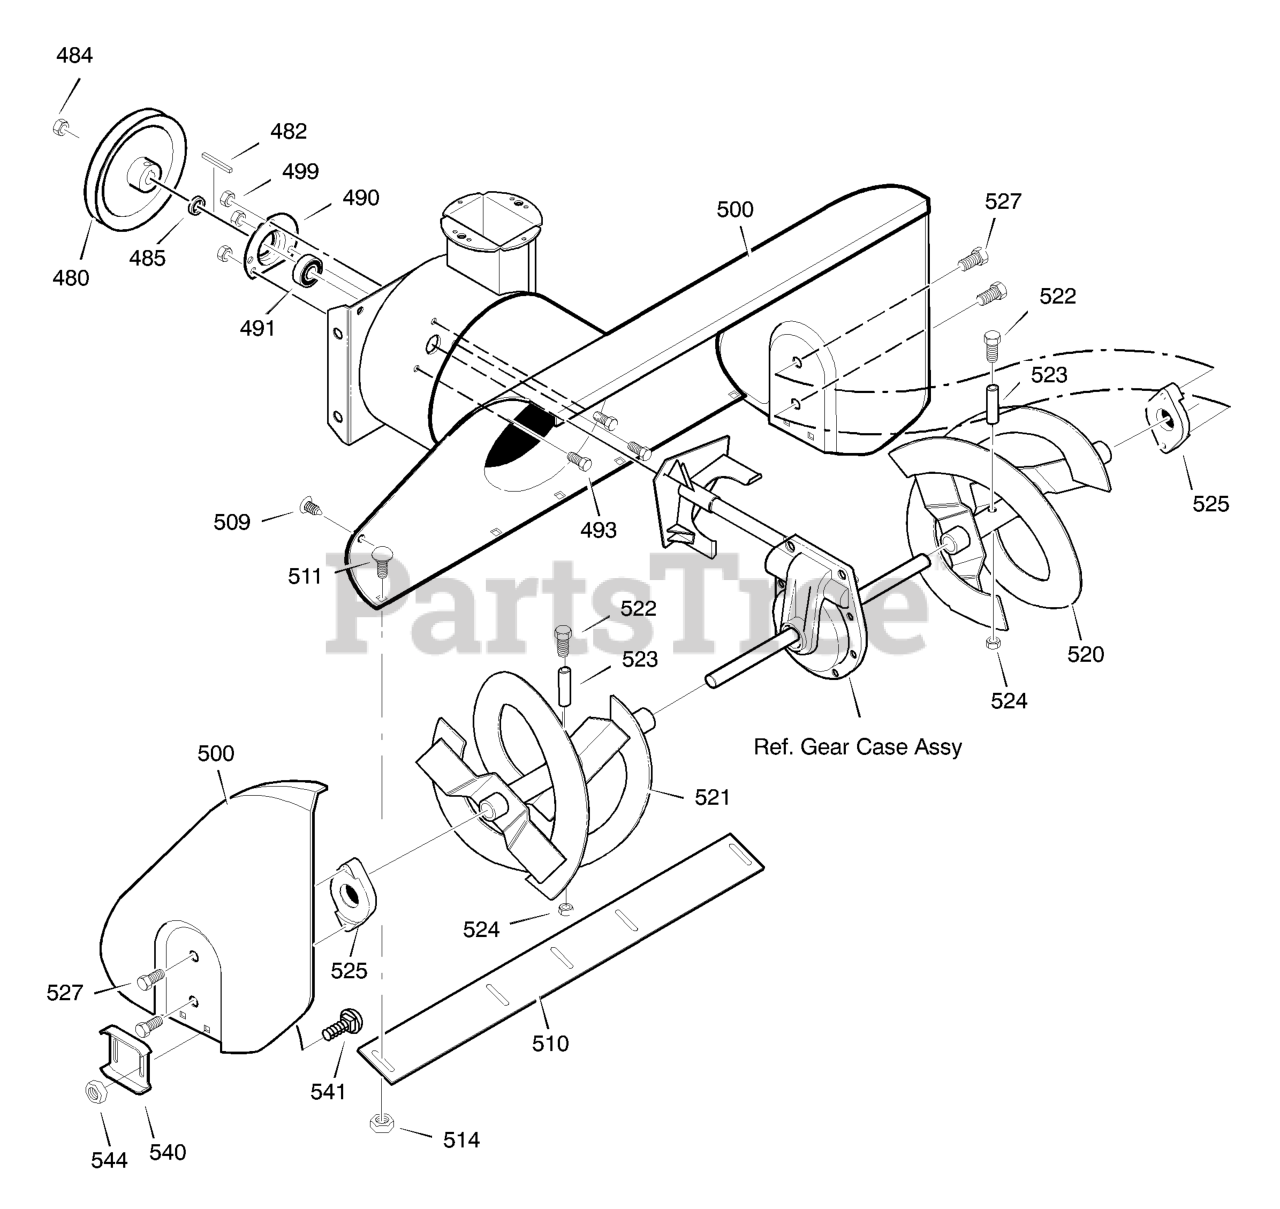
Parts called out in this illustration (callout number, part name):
480	PULLEY, 4L 8.40 OD
482	KEY, SQUARE
484	NUT, 1/2-20
485	SPACER, FRICTION PULLEY
490	RETAINER, BALL BRNG
491	BEARING, BALL
493	BOLT, HEX - 0.31-18X0.50
499	NUT, 5/16-18 HEXWDFLLK
500	HOUSING, ASSY
509	PLUG, CHRISTMAS TREE
510	BLADE, SCRAPER
511	BOLT, CARRIAGE
520	AUGER, ASSY, LH
521	AUGER, ASSY, RH
522	BOLT, 1/4-20 x 1.75
523	SPACER, SLEEVE
524	NUT, 1/4-20
525	BEARING, AUGER SHAFT 1" ID
527	SCREW, 5/16-18 x 0.75
536	BOLT, 5/16-18 x .75
540	SKID, HEIGHT ADJUST
541	BOLT, 5/16-18 X .75
544	NUT, 5/16-18 REGHEX
